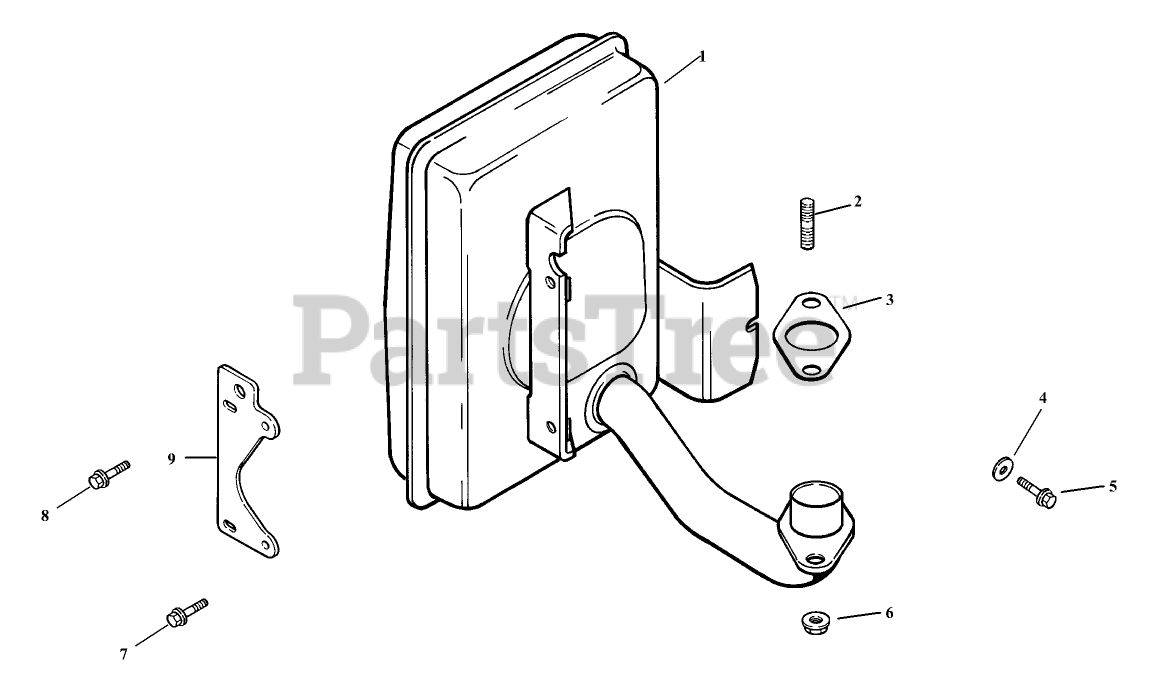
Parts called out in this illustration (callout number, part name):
1	Muffler
2	STUD (M8X1.25X33)
3	Gasket-Manifold, Exhaust
4	Washer-Plain (1/4in)
5	SCREW-FLANGE, THREAD FORMING (M5X0.8X16)
6	NUT-FLANGE (M8X1.25)
7	SCREW-FLANGE, THREAD FORMING (M6X1.0X16)
8	SCREW-FLANGE, THREAD FORMING (M6X1.0X25)
9	Bracket-Muffler
